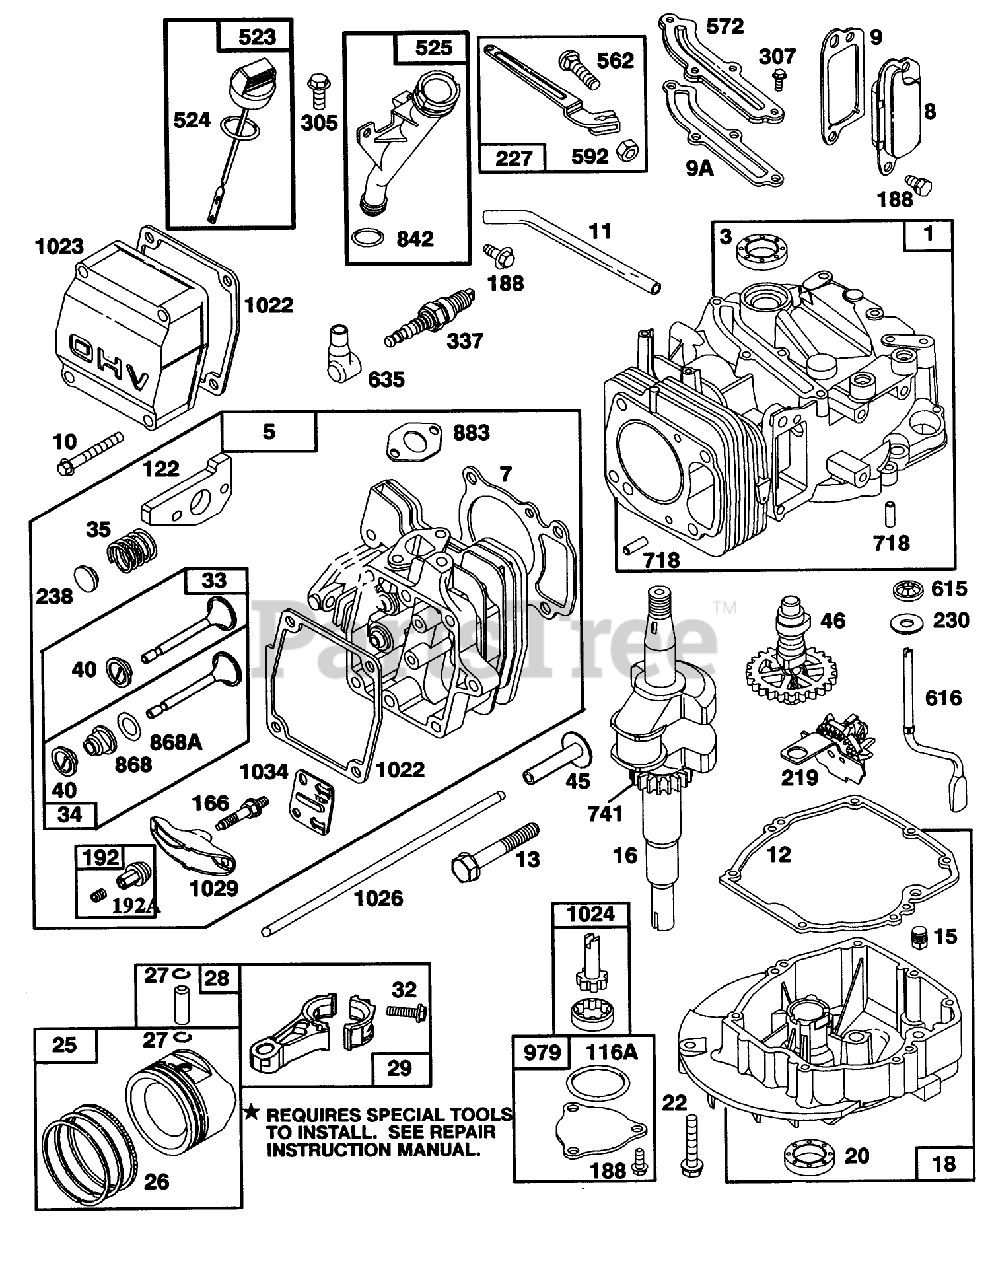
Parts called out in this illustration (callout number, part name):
1	CYLINDER ASSEMBLY
7	CYLINDER HEAD GASKET
10	HEX HEAD SCREW
11	BREATHER TUBE
12	ENGINE BASE GASKET
20	SEAL-OIL
25	STD PISTON ASSEMBLY
27	PISTON PIN LOCK
29	CONNECTING ROD
33	EXHAUST VALVE
34	INTAKE VALVE
35	VALVE SPRING
45	VALVE TAPPET
116A	O RING SEAL
122	ADAPTER ASSEMBLY
166	ROCKER ARM STUD
188	SCREW - SEM
219	GOVERNOR/OIL SLINGER
227	GOVERNOR LEVER ASSEMBLY
305	SCREW - HEX HEAD
307	SCREW - SEM
337	PLUG-SPARK
524	O-RING
562	GOVERNOR LEVER BOLT
592	HEX NUT
635	SPARK PLUG ELBOW
842	O-RING
979	OIL PUMP COVER
1022	ROCKER COVER GASKET
1024	OIL PUMP
1026	PUSH ROD
1029	ROCKER ARM
1034	PUSH ROD GUIDE
